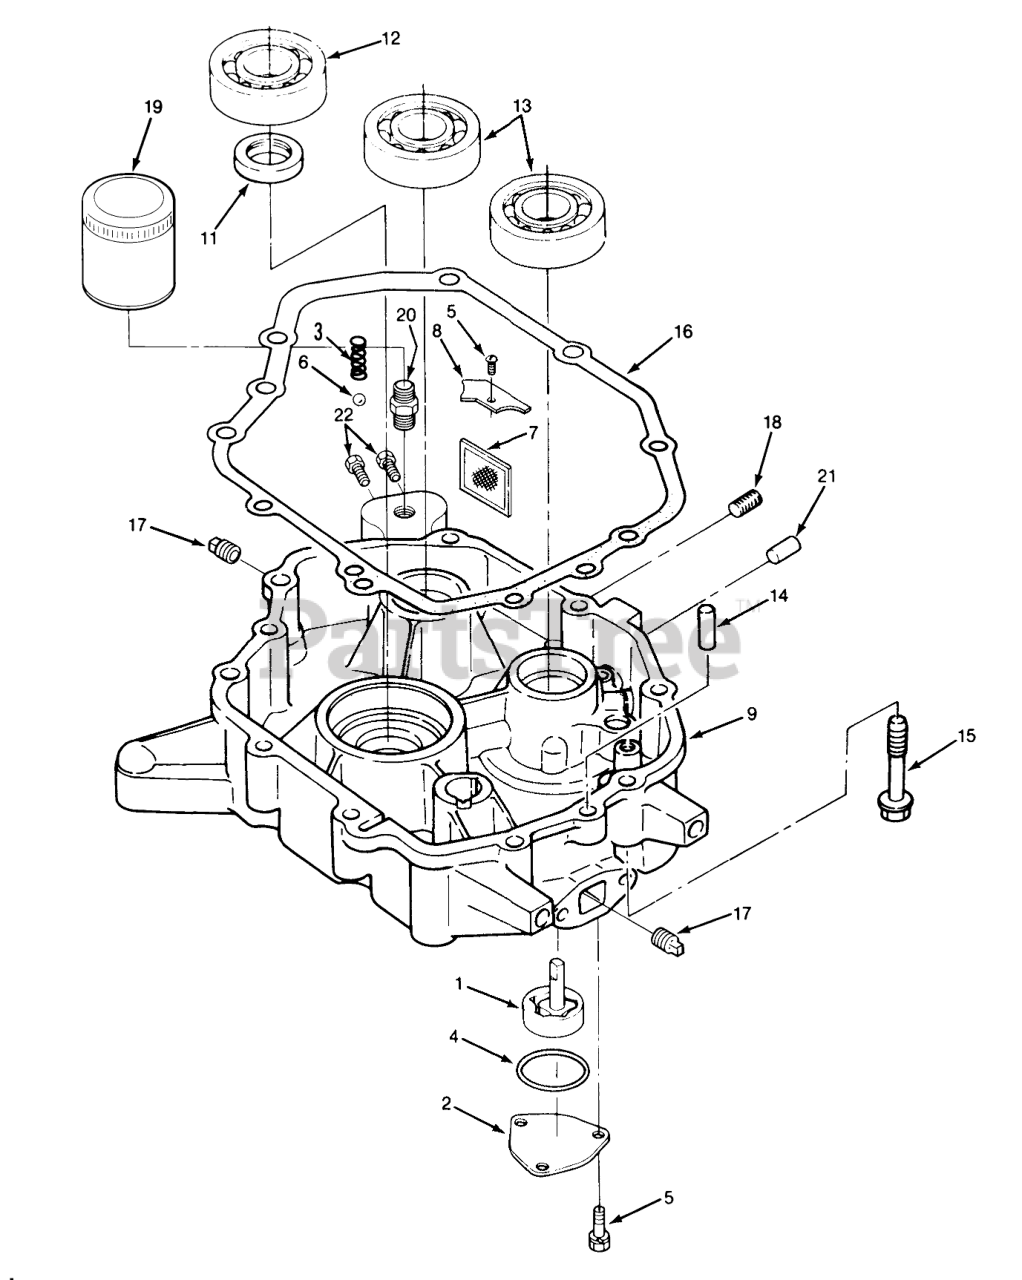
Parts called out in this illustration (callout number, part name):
1	PUMP-OIL
2	COVER-OIL PUMP
3	SPRING-RELIEF VALVE
4	RING-O
5	SCREW
6	BALL-BEARING
7	SCREEN
8	COVER
9	BASE-0IL
11	SEAL-OIL CRNKSHFT UP
12	BRNG-BALL CRANKSH L
13	BRNG-BALL BAL SHFT L
14	PIN-ALIGNMENT
15	SELF-TAP BOLT SP M8
16	Gasket
17	Plug
18	Plug
19	FILTER
20	ADAPTER
22	PLUG-HEX HD
